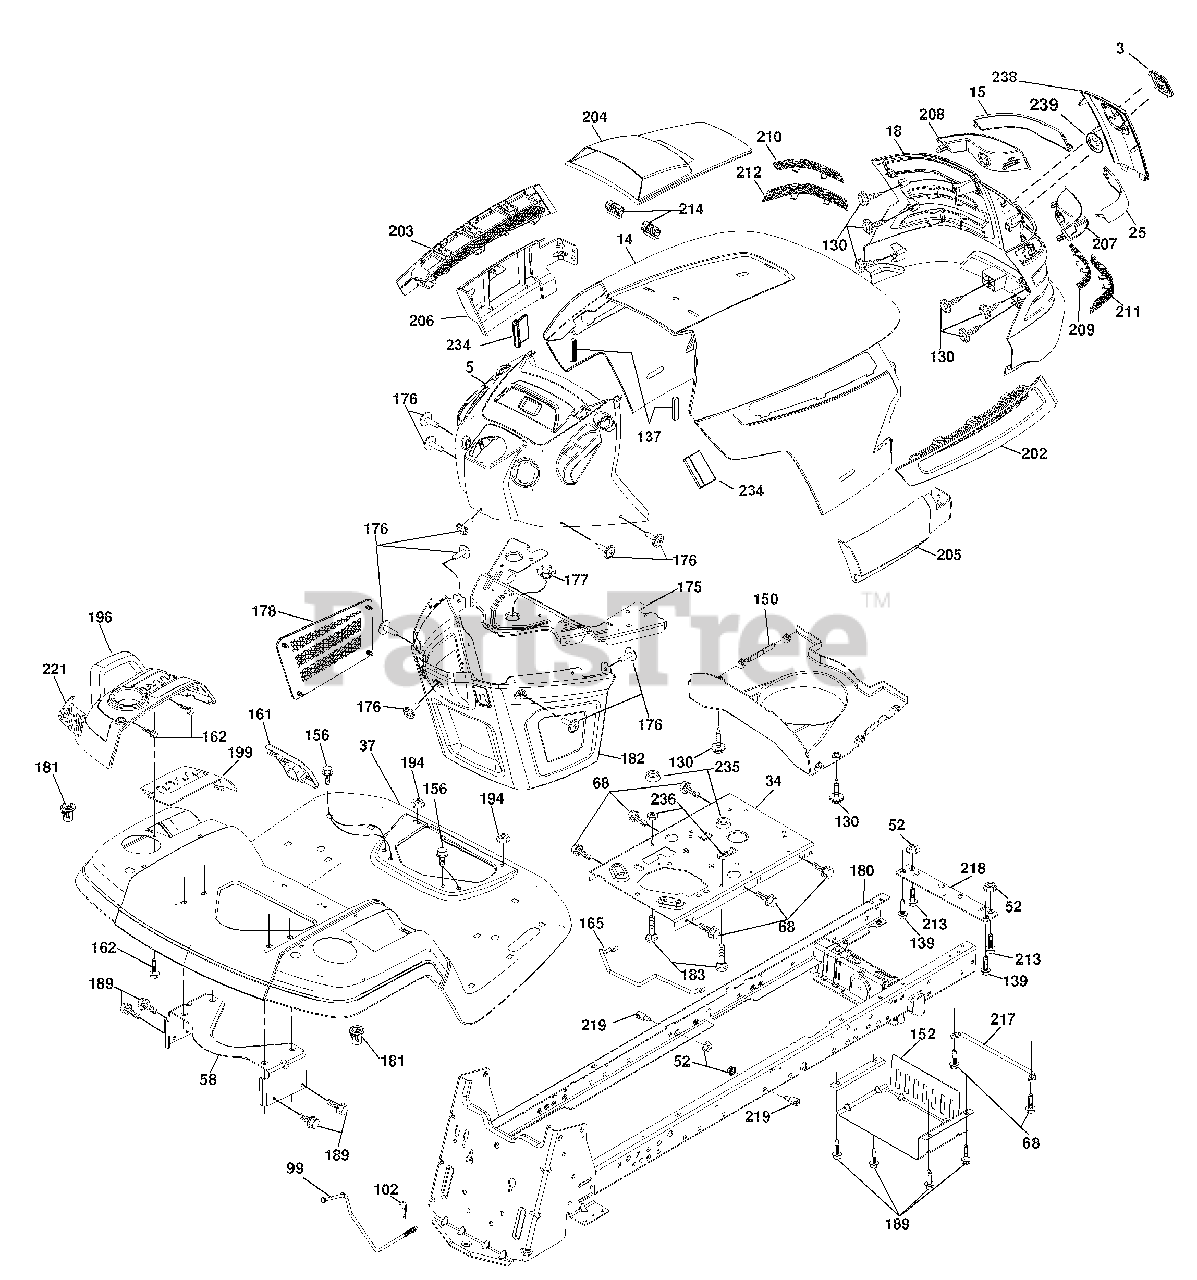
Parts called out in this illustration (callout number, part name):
3	Logo
14	Hood
34	Plate Engine
37	Fender
52	Nut Crown Lock 5/16-18
58	Bracket Fender
68	Screw 5/16-18 x 1/2
99	Rod Bypass Asm.
102	Retainer Spring 1"
130	Screw 10 x 3/4 Single Lead Hex
137	Bumper Dash
139	Screw 5/16-18 x 1/2
150	Duct Heat Hood
152	Shield Browning/Debris
156	Screw 5/16-18 x 3/4
161	Console Fuel Window
162	Screw Hex Wsh Hi-Lo 1/4 x 1/2
165	Bracket Support Tank
175	Crossmember
176	Screw 10-24 x 5/8 Wshd Qdrx
177	Bushing Steering
178	Cargo Asm. Net
180	Chassis
181	Bushing Mtg. Fender Crgo.
182	Dash Lower
183	Bolt 5/16-18 UNC x 1-1/4
189	Screw 5/16-18 x 3/4
194	Nut Lock Hex Flange 5/16-18
196	Console Asm. Deck Lift
199	Plate Deck Lift
202	Vent Side Hood RH
203	Vent Side Hood LH
204	Vent Asm Hood Top
205	Skirt Hood Side RH
206	Skirt Hood Side LH
209	Insert Hex Top RH
210	Insert Hex Top LH
211	Insert Hex Bottom RH
212	Insert Hex Bottom LH
213	Bolt Hex Hd 5/16-18 unc x 3/4
214	Clip Retainer
217	Rod Pivot
219	Stud Fastener
221	Reflector LH
234	Bumper Hood
235	Spacer Fender
236	Nut Center Lock 5/16-18 UNC
